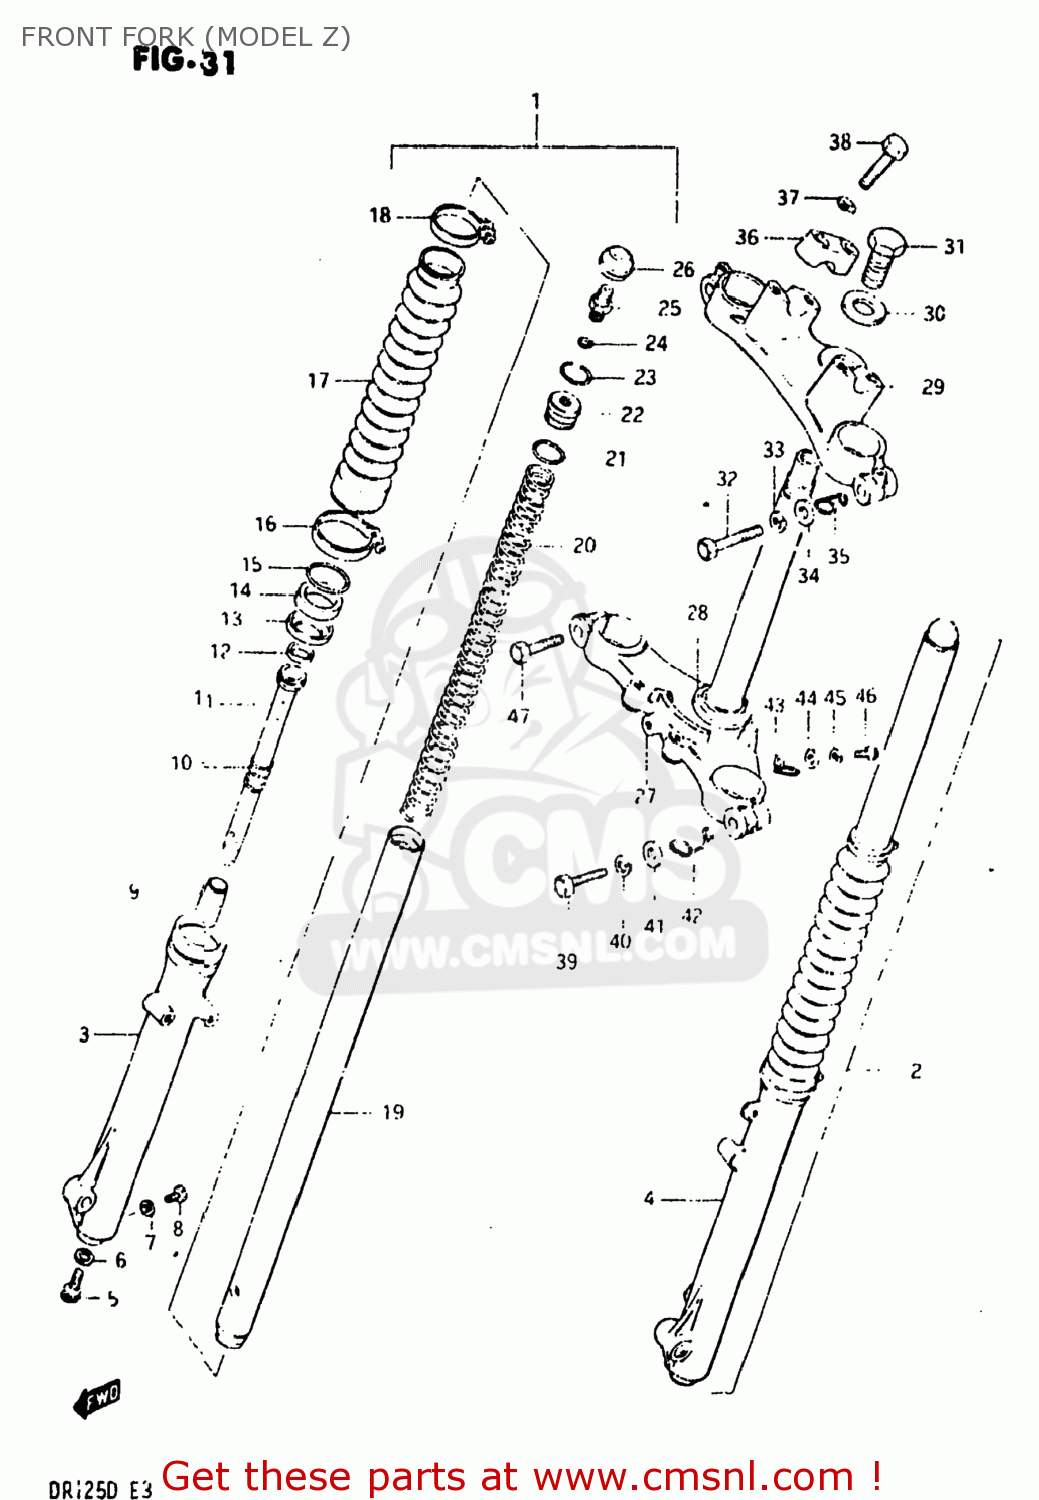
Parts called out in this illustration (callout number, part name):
1	DAMPER ASSEMBLY,RIGHT
2	DAMPER ASSEMBLY,LEFT
3	TUBE,FORK,OUTER,RIGHT
4	TUBE,OUTER,LEFT
5	BOLT(8X27)
6	GASKET (NAS)
7	GASKET,DRAIN,PLUG (NAS)
8	BOLT
9	PIECE,OIL LOCK
10	SPRING,REBOUND
11	CYLINDER,FRONT FORK
12	RING,PISTON
13	SPACER
14	OIL SEAL,FRONT FORK
15	RING,OIL SEAL STOPPER
16	CLAMP
17	BOOT
18	BAND
19	TUBE,FORK INNER
20	SPRING,FRONT FORK
21	O RING
22	SEAT,SPRING
23	RING,STOPPER
24	O-RING
25	VALVE,AIR
26	CAP,FRONT FORK
27	STEM, STEERING
28	RACE,STEERING OUTER LWR
29	HEAD,STEERING STEM
30	WASHER,STEM HEAD(10.5X30X3.2)
31	BOLT,FORK INNER TUBE
32	BOLT
33	LOCK WASHER
34	WASHER
35	GUIDE,CABLE
36	HOLDER,HANDLEBAR
37	LOCK WASHER
38	BOLT,HANDLE HOLDER
39	BOLT 12X45
40	WASHER,LOCK 12
41	WASHER
42	CLIP,CABLE
43	CLIP
44	WASHER
45	LOCK WASHER
46	SCREW 6X12
47	BOLT
